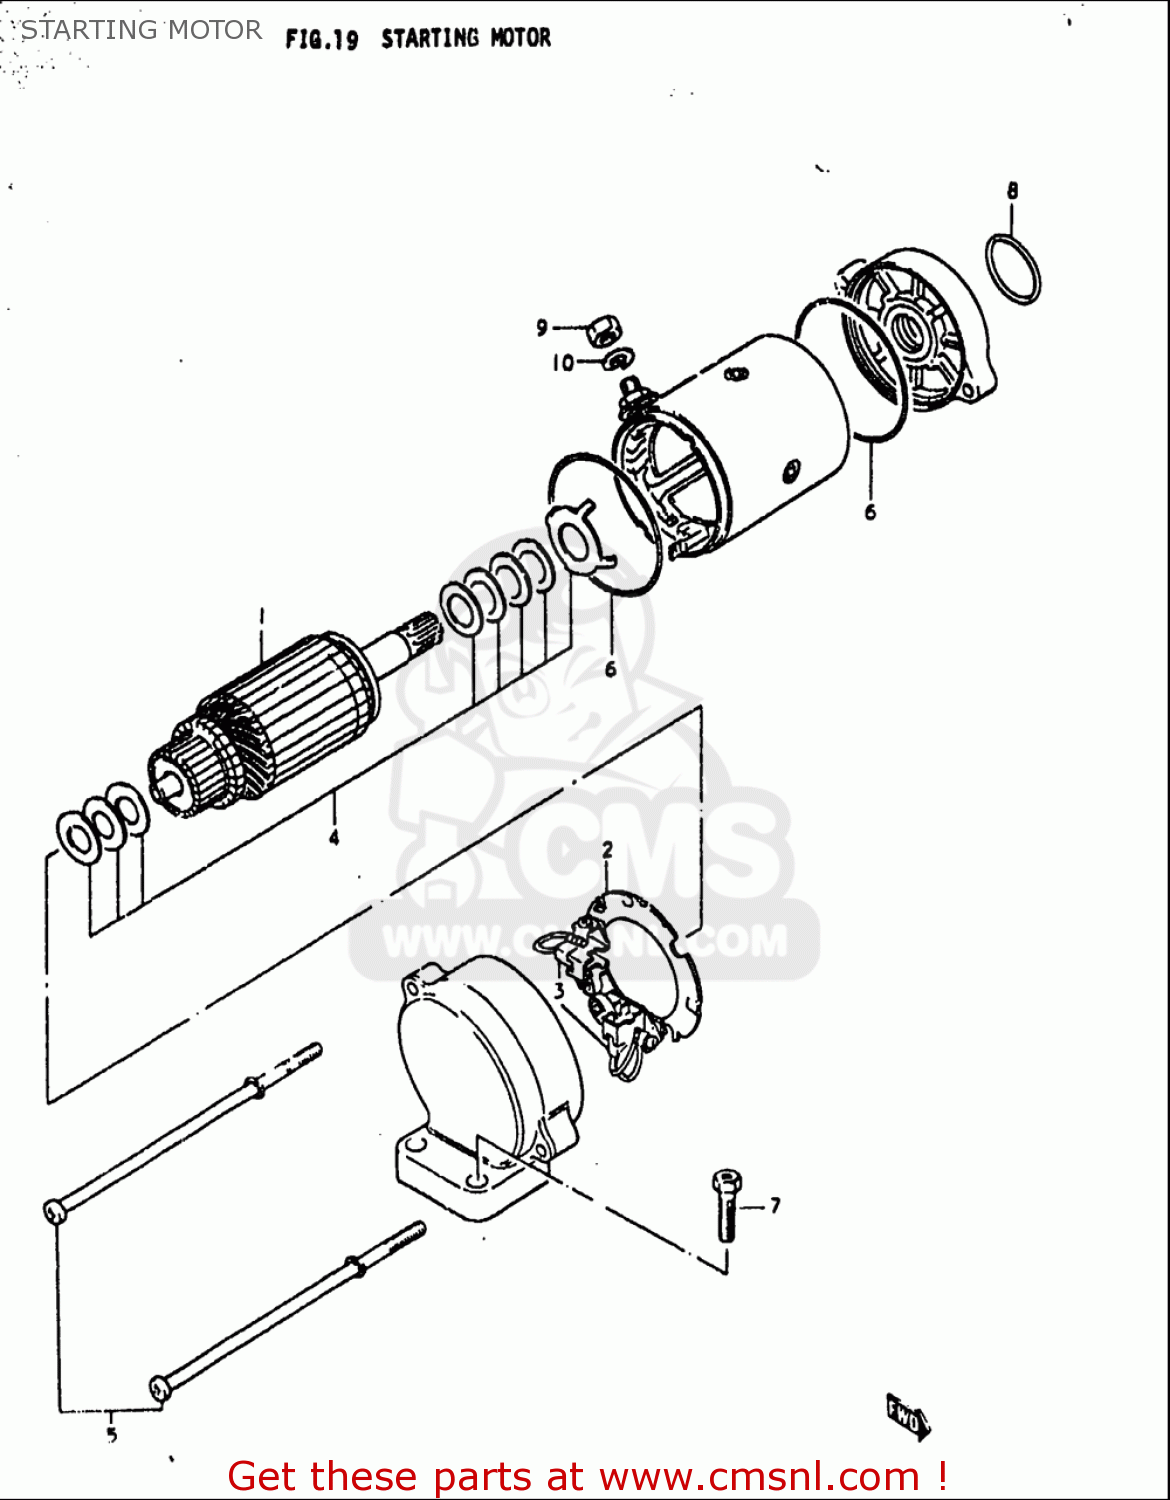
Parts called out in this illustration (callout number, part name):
2	HOLDER ASSY
3	BRUSH SET
5	BOLT
6	O RING
7	SCREW (6X25)
8	O RING(D:2,ID:24.5)
9	NUT
10	WASHER,LOCK
